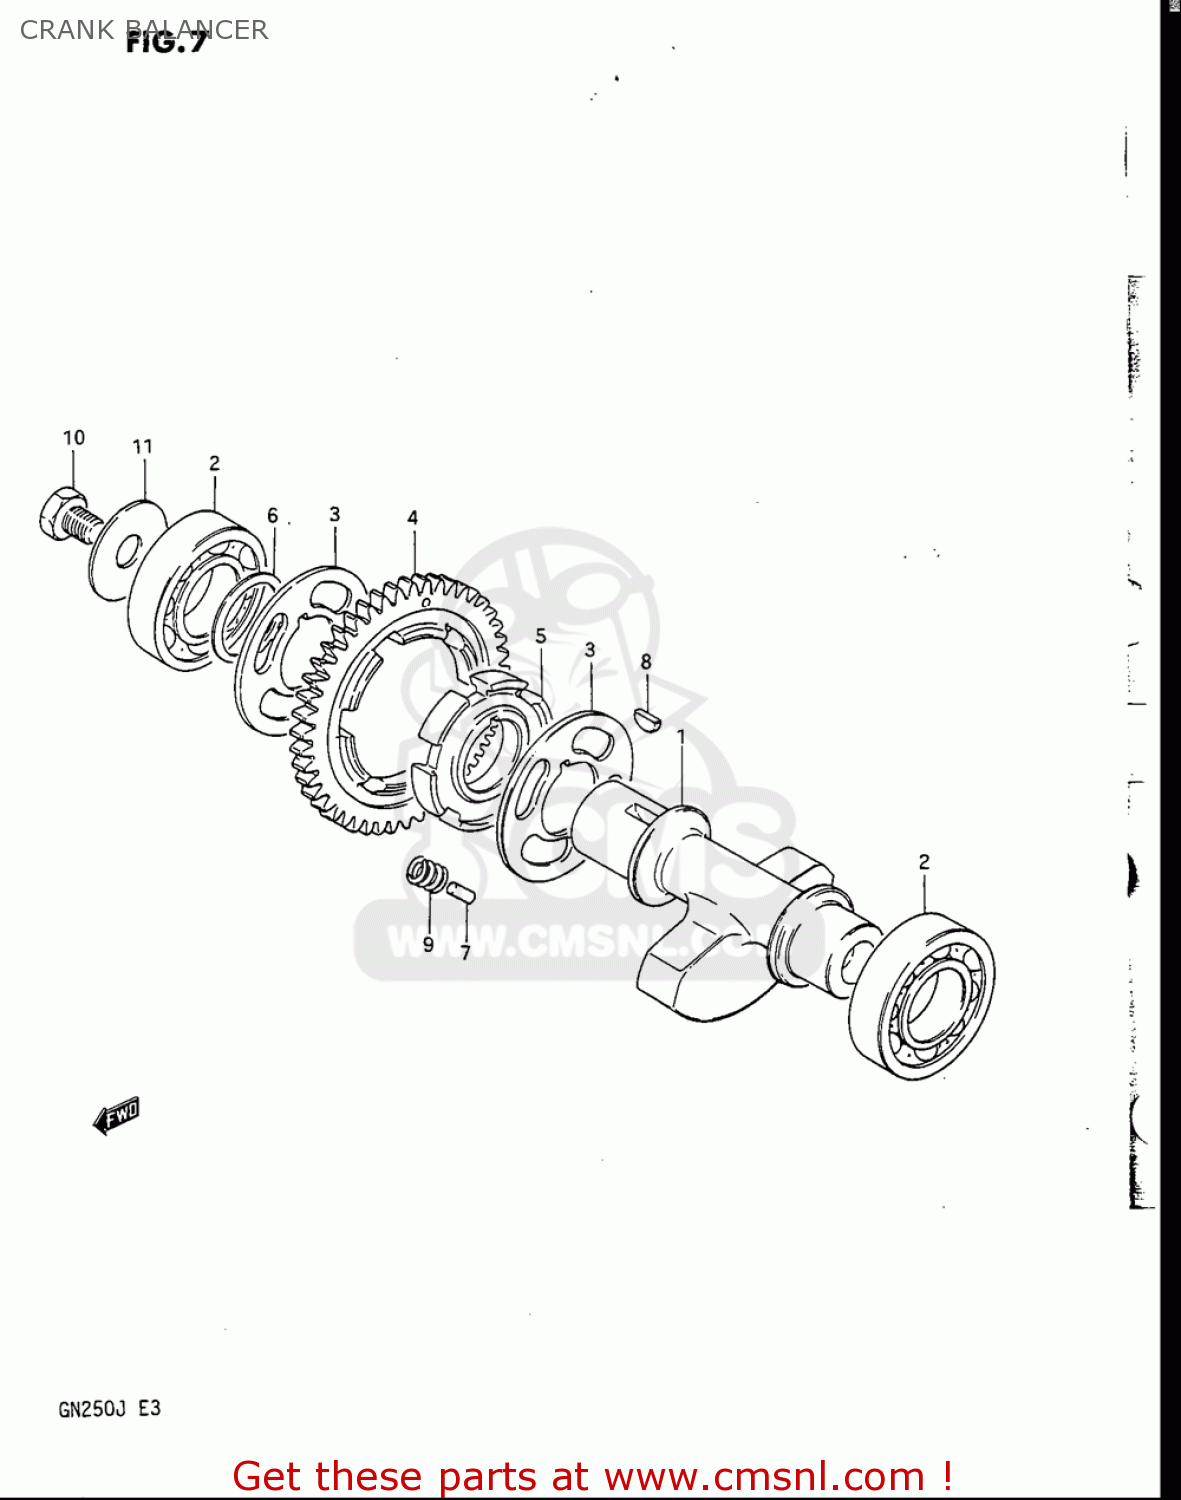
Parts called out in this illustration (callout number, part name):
1	SHAFT,CRANK BALANCER
2	BEARING(25X62X17)
3	WASHER
4	GEAR,CRANK BAL DRIVEN(NT:46)
5	RACE,CRK BAL DRIVEN GR INNER
6	SHIM(25X36X0.5)
7	PIN(4.5X9.5)
8	KEY
9	SPRING
10	Bolt
11	WASHER(12X40X2.5)
